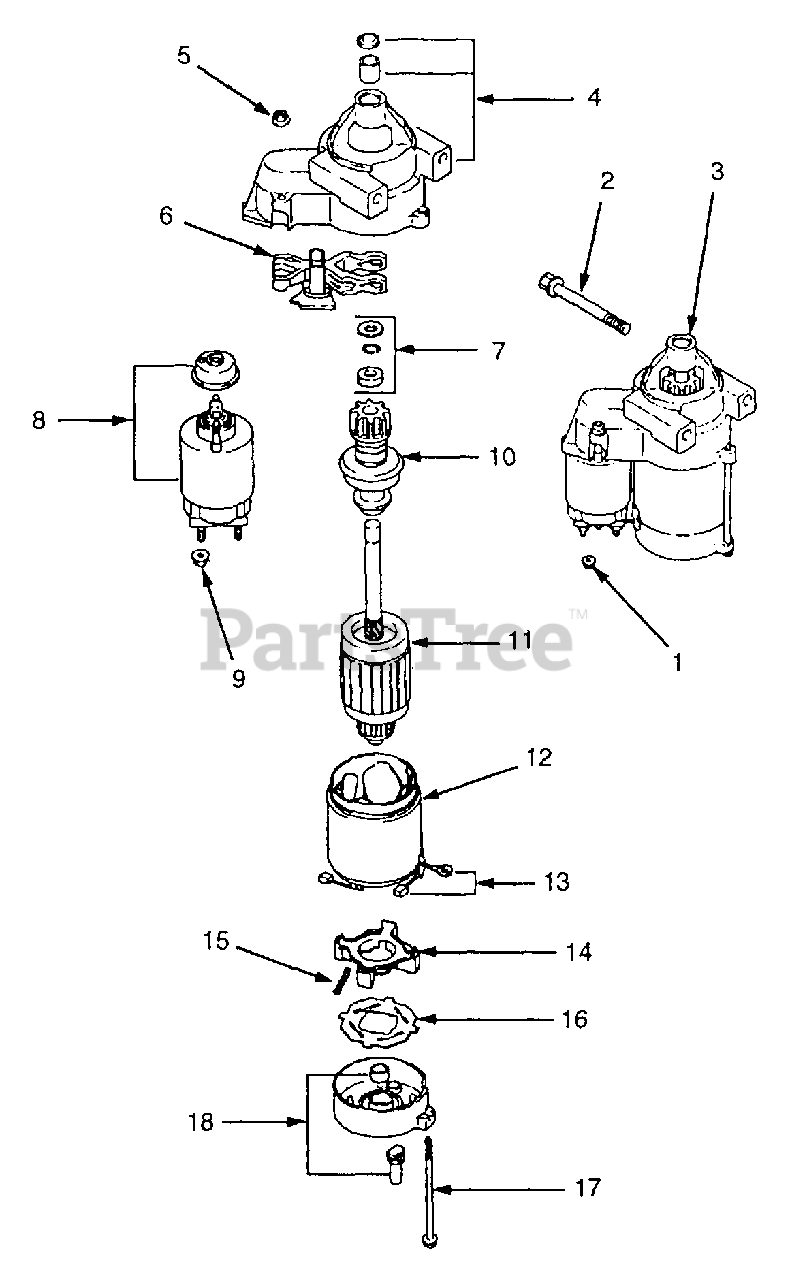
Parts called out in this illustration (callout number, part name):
1	Nut, Hex Flange, M8 x 1.25
2	Screw, Hex Flange, M8 x 1.25 x 80
3	Starter, Solenoid Shift
4	Drive, End Cap
6	Lever, Starter Drive
7	Kit, Starter Repair
9	Nut
10	Drive, Pinion
13	Kit, Brush
14	Holder, Brush
15	Spring, Brush
17	Bolt, Thru, M5 x 0.8 x 99
18	Commutator, End Cap
